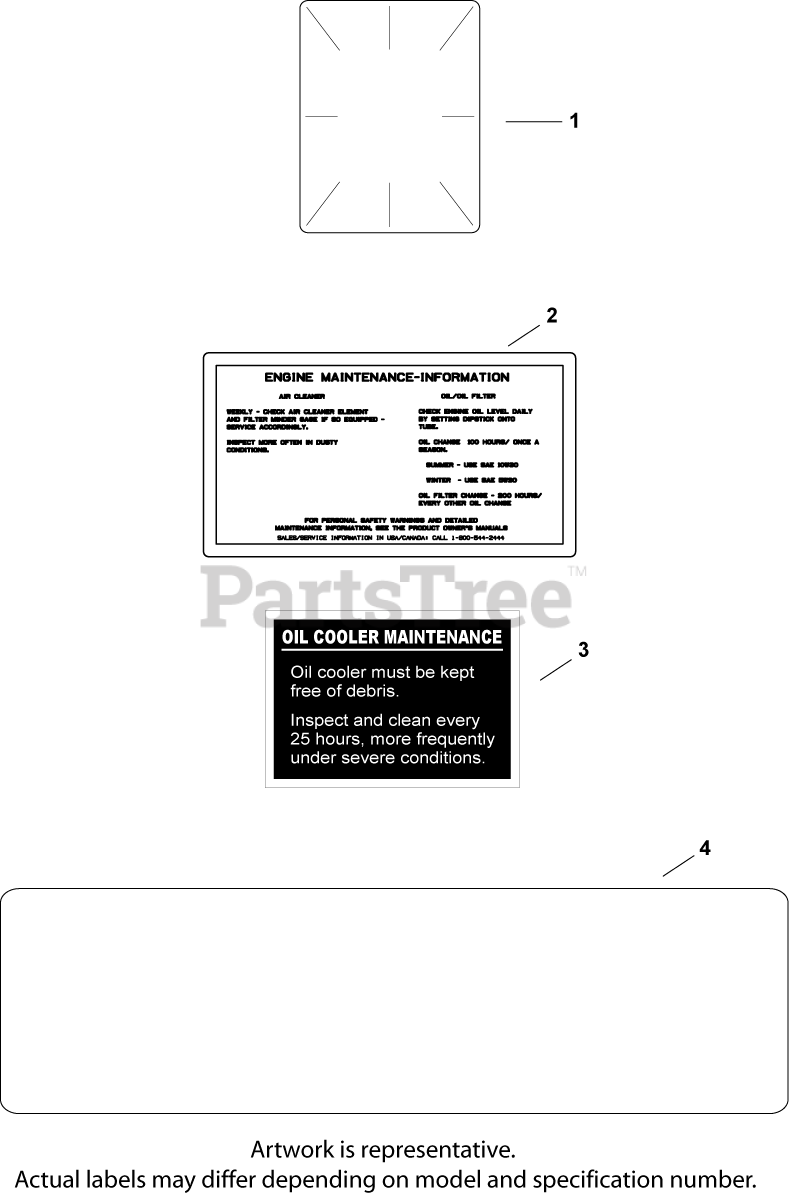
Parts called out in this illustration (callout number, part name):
1	DECAL, CLEAR LAMINATE USE 25 113 70-S
2	DECAL, AIR CLEANER - (#DSC)
3	DECAL, OIL COOLER - (#DSC)
4	DECAL, 27 HP - DISCONTINUED
